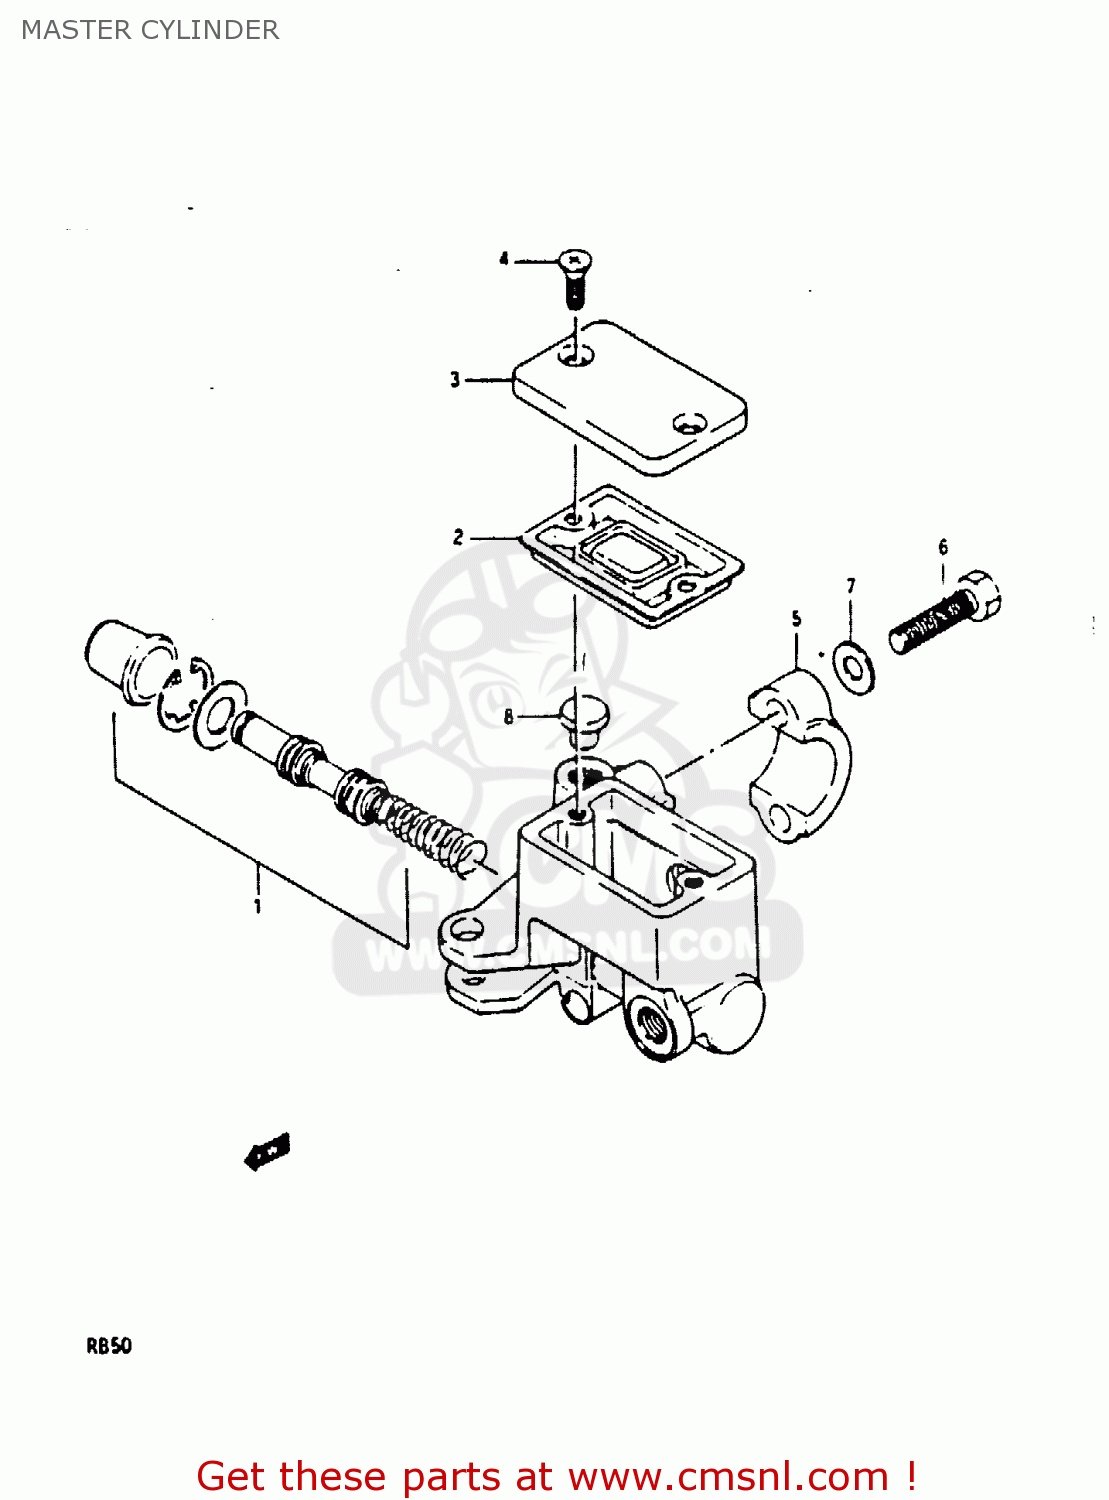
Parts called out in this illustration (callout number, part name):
1	PISTON & CUP SET
2	DIAPHRAGM
3	CAP
4	SCREW
5	HOLDER
6	BOLT
7	WASHER
8	PLUG(OD:12)
